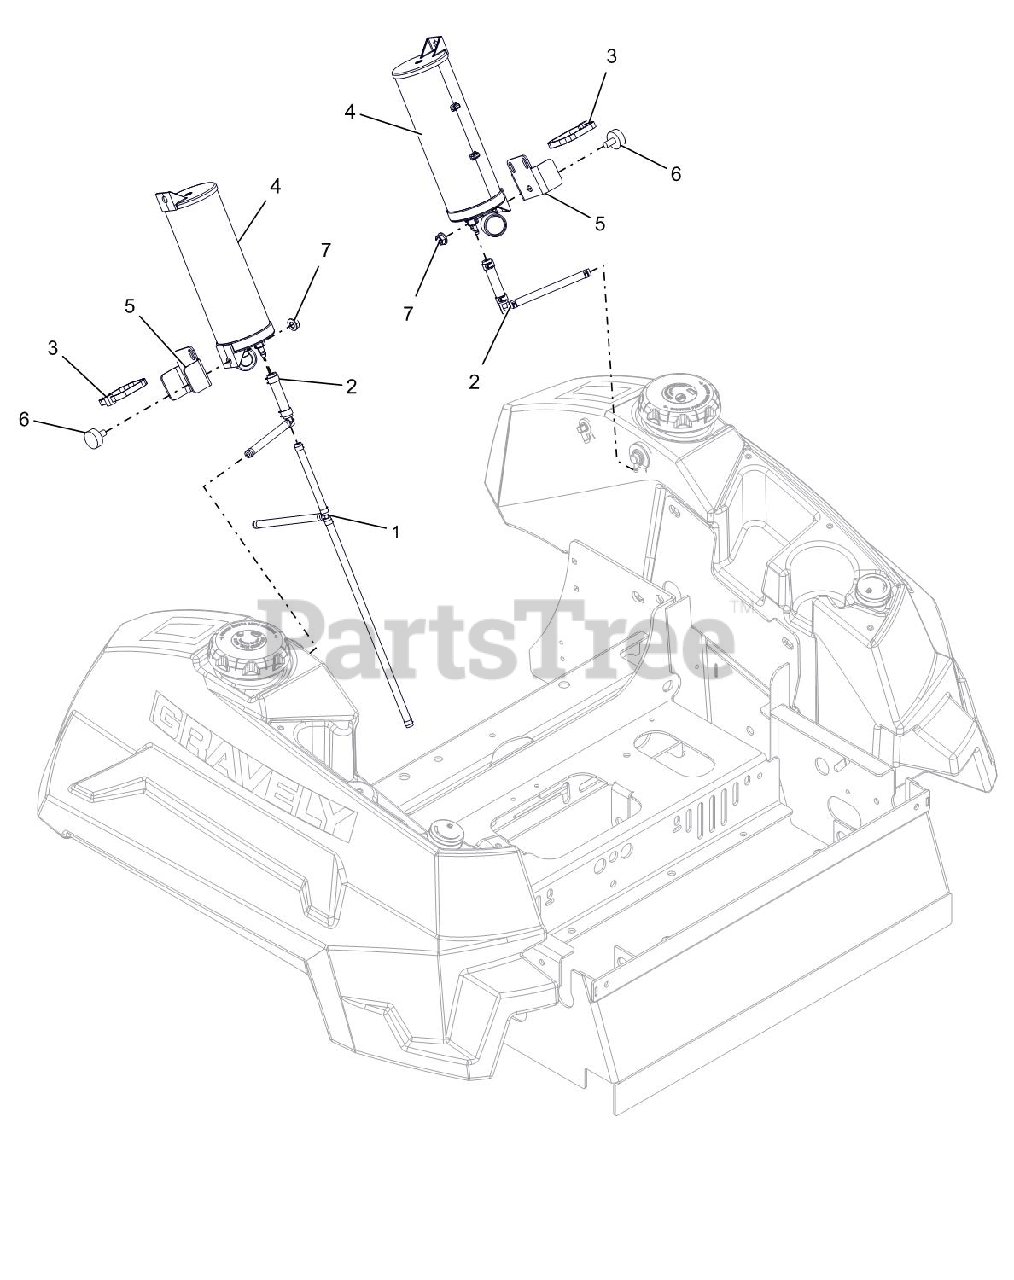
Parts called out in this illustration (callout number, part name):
1	ASM, YAMAHA VAPOR LINE (CARB)
2	ASM, CANISTER VENT LINE
3	TIE WRAP, 15.25" X 120 LBS
4	CANISTER, CARBON 9.3G CAP.
5	CARB CANISTER MTG BRKT - BLACK
6	BUMPER, RUBBER
7	@NUT-SPNLK-FLG .312-18 YWZC
